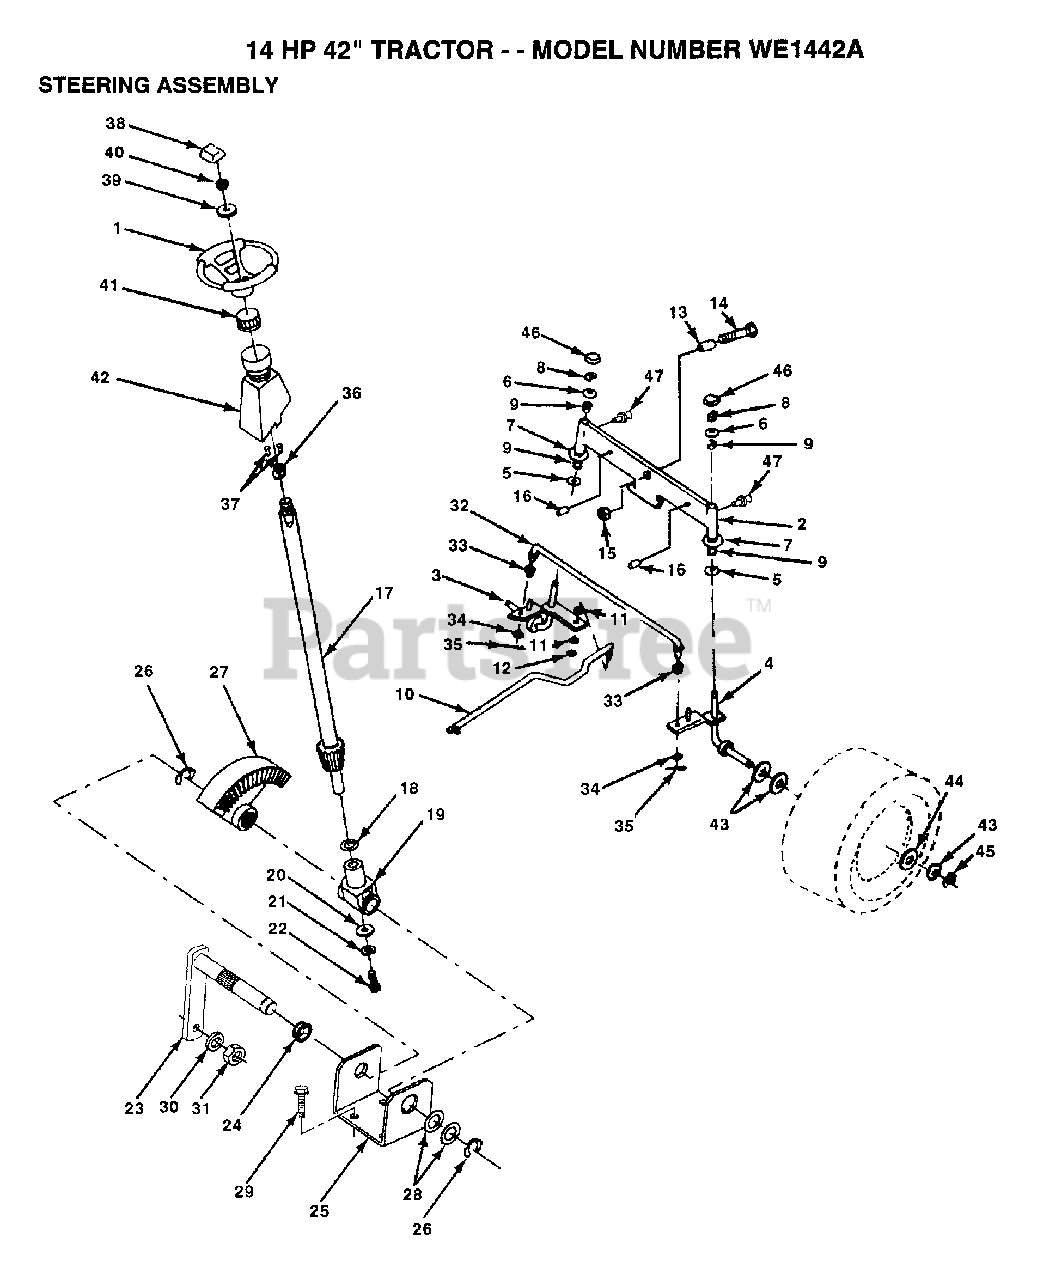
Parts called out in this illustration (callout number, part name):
3	SPINDLE LH
4	SPINDLE RH
5	WASHER .T
6	WASHER
7	WASHER
8	RING
9	COL. SRTG. BEAR.
11	LOCKWASHER
13	BEARING
14	BOLT HEX 5/8-11
15	"NUT-LOC,FLANGE LT"
16	AXLE PIN
17	SHAFT ASM
18	THRUST WASHER
19	SUPPORT.SHAFT
21	LOCKWASHER
22	"SCREW,SPECIAL"
24	NYLINER T
25	"BRKT,STEERING"
26	RING
27	GEAR SECTOR
28	WASHER .T
29	SCREW
30	LOCKWASHER
32	TIE ROD
33	BUSHING.DRAGLINK
34	WASHER
35	COTTER PIN
38	ST WHL INSERT CAP
39	WASHER T
40	GRIPCO NUT
41	ADAPTER-WHEEL LT
42	"TUBE, STR SHAFT"
43	WASHER
44	WASHER
45	RING
46	CAP
47	ZERK M
